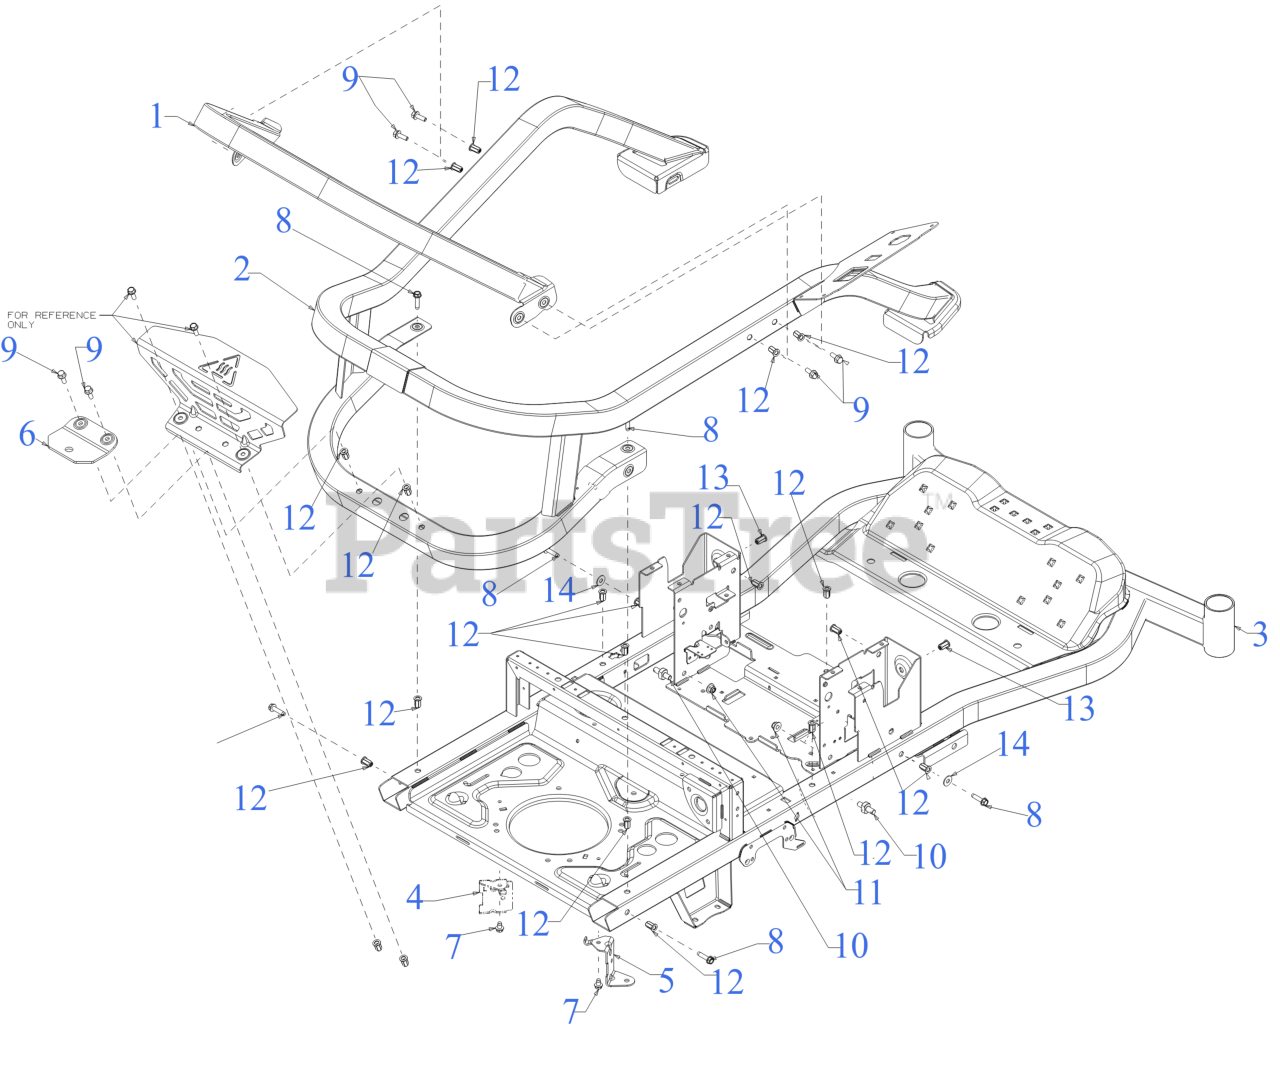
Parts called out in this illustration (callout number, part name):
1	UPPER FRAME HOOP
2	UPPER FRAME
3	FRAME
4	TRANSMISSON MOUNT SUPPORT (LH)
5	TRANSMISSON MOUNT SUPPORT (RH)
6	HITCH PLATE
7	SCREW 5/16-18 x .500
8	SCREW 5/16-18 x 1.25
9	SCREW 5/16-18 x .875 GR5 HXFLG HD
10	SHOULDER STUD
12	NUT RIVET 5/16-18
13	NUT RIVET 5/16-18
14	FLAT WASHER
